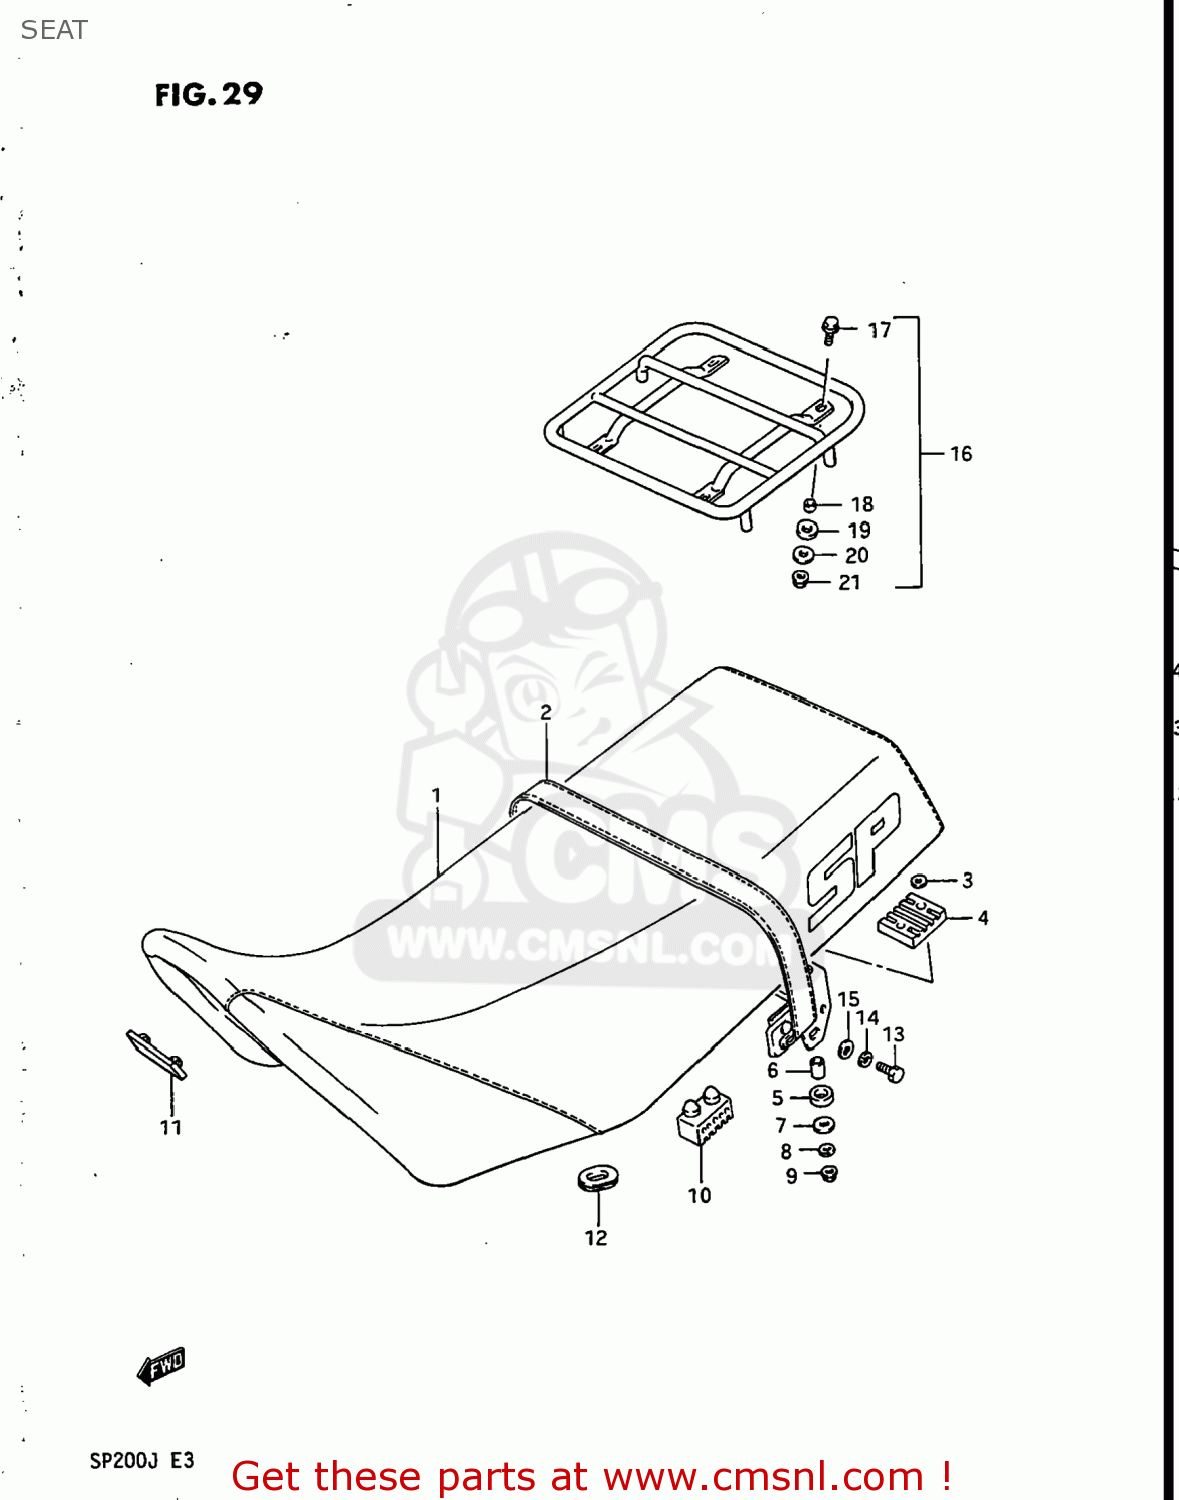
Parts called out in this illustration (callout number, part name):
1	SEAT ASSEMBLY
2	BAND,SEAT
3	WASHER, LOWER
4	CUSHION,FR PLATE
5	CUSHION,SEAT FR
6	SPACER,SEAT SUPPORT
7	WASHER
8	WASHER,LOCK
9	NUT
10	CUSHION,SEAT(40X20X15)
11	CUSHION
12	CUSHION
13	BOLT
14	WASHER,LOCK,8.
15	WASHER
16	CARRIER SET,SUPPORT
17	BOLT
18	SPACER
19	CUSHION
20	WASHER(6.5X18X1)
21	NUT 6MM
